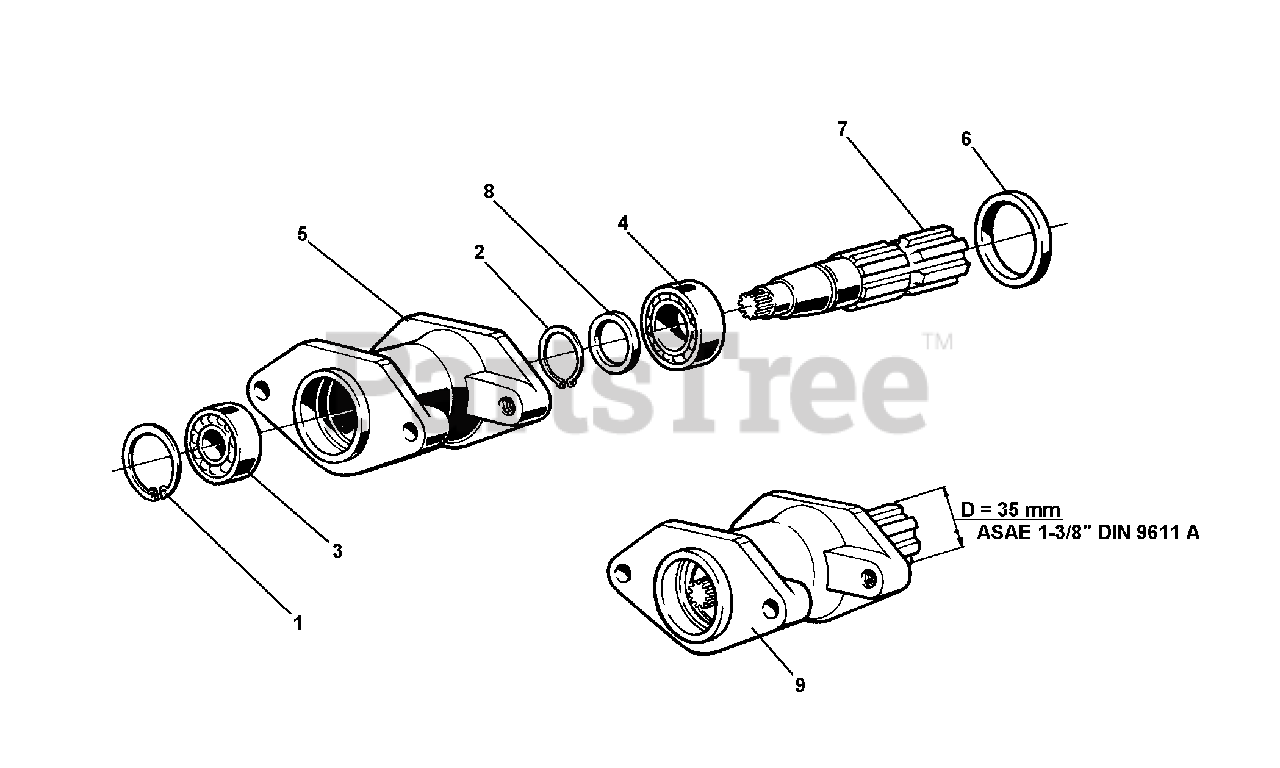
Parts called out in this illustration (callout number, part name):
1	CIRCLIP, INTERN. D 47
2	CIRCLIP, EXTERN. D 30
3	BEARING 20 X 47 X 14 6204 2RS ST
4	BEARING 30 X 55 X 13 6006 2RS ST
5	P.T.O. CASING D. 35
7	P.T.O. SHAFT D.35
9	POWER TAKEOFF 1 3/8"
